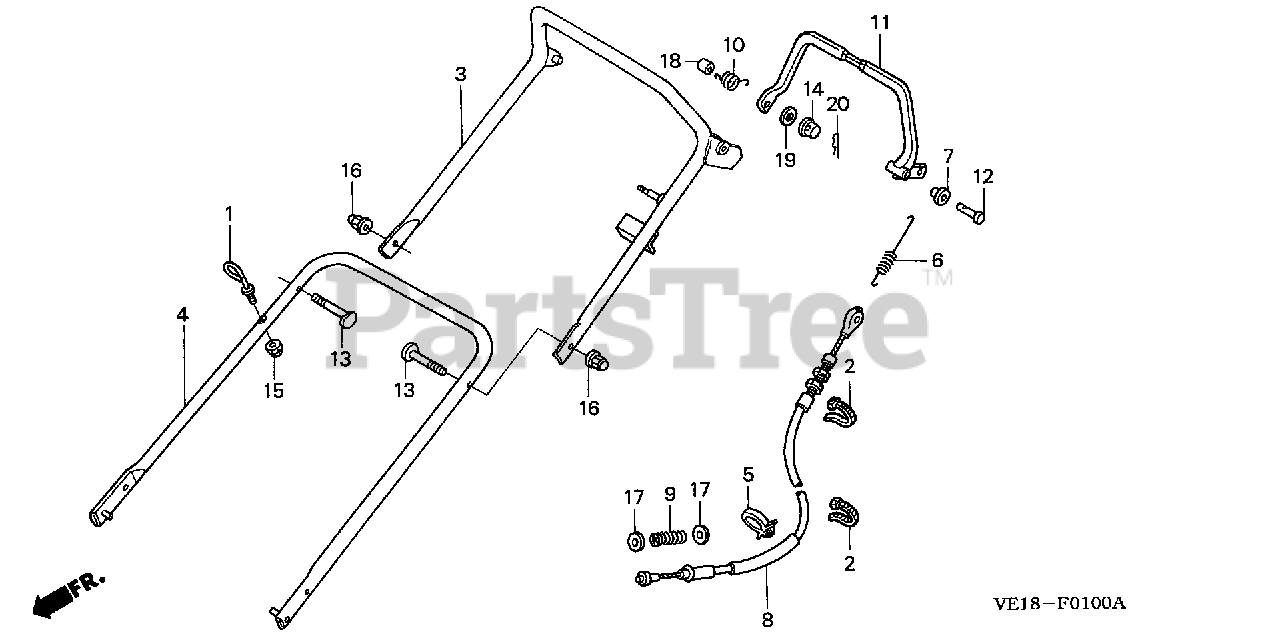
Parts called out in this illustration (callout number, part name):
1	GUIDE, ROPE
2	TIE, CABLE (157.5MM)
3	PIPE, HANDLE (UPPER) *NH105* (MAT BLACK)
4	HANDLE (LOWER) *NH105* (MAT BLACK)
5	CLIP, POWER STEERING SUCTION TUBE
6	SPRING, CLUTCH
7	BUSH, CLUTCH LEVER
8	CABLE, BRAKE
9	SPRING B, BRAKE
10	SPRING, R. STOP RETURN
11	LEVER, BRAKE *NH105* (MAT BLACK)
12	PIN, CLUTCH LEVER
13	BOLT, HANDLE HOLDER (8X36)
14	NUT, PUSH (8MM)
15	NUT, NYLON LOCK (6MM)
16	NUT, CAP (8MM)
17	WASHER, SPECIAL (6MM)
18	COLLAR (8X11X13.5)
19	WASHER, PLAIN (8MM)
20	PIN, LOCK (8MM)
